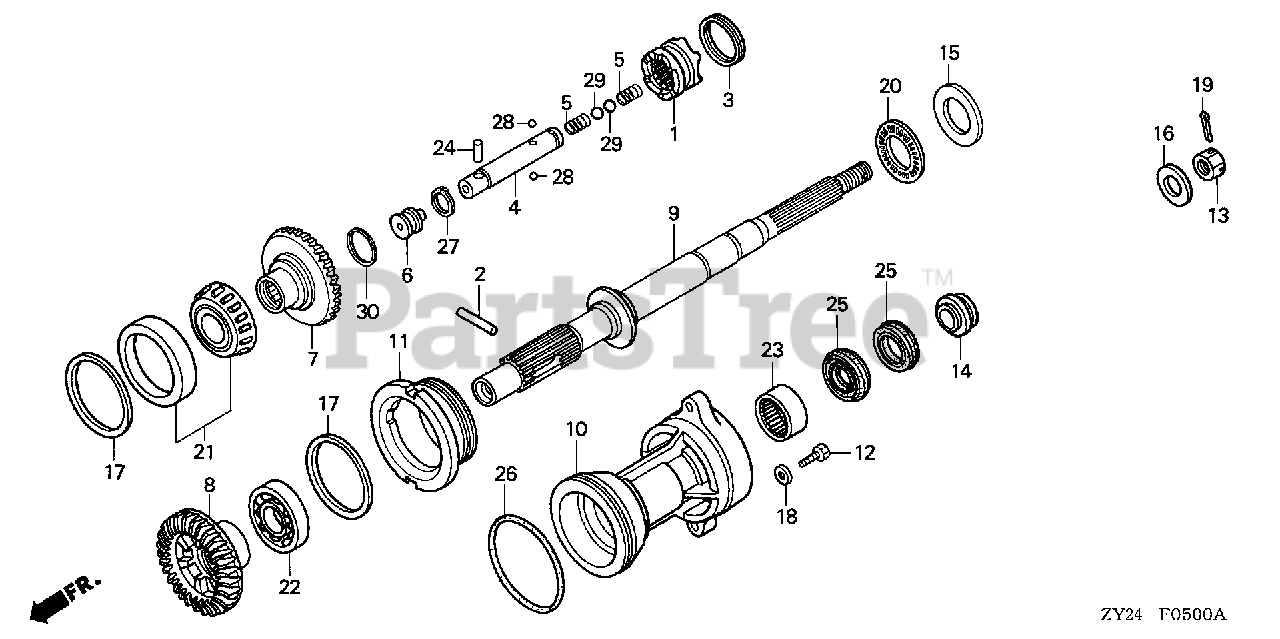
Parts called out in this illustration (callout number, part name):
1	SHIFTER, CLUTCH
2	PIN, SHIFTER (8X50)
3	RING, CROSS PIN
4	SLIDER, SHIFT
5	SPRING, SHIFT
6	PLATE, SHIFT
7	GEAR, FR. BEVEL (28T)
8	GEAR, BEVEL (RVS. 28T)
9	SHAFT, PROPELLER
10	HOLDER, PROPELLER SHAFT *NH282MU* (OYSTER SILVER METALLIC-U)
11	HOLDER, BEARING
12	BOLT, HEX. (12X45)
13	NUT, CASTLE (18MM)
14	WASHER, PROPELLER THRUST
15	WASHER, THRUST BEARING
16	WASHER, PROPELLER
17	SHIM A, BEVEL (0.10)
17	SHIM B, BEVEL (0.15)
17	SHIM C, BEVEL (0.30)
17	SHIM D, BEVEL (0.50)
18	WASHER, PLAIN (12MM)
19	PIN, SPLIT (4.0)
20	BEARING, THRUST (F)
21	BEARING, TAPER (50X90X21.5)
22	BEARING, ANGULAR (50X90X30.2)
23	BEARING, NEEDLE (32X42X30)
24	ROLLER (4X13.8)
25	SEAL, WATER (30X45X7)
26	O-RING (105X3.1)
27	CIRCLIP (OUTER) (15MM)
28	BALL, STEEL (#7) (7/32)
29	BALL, STEEL (#12) (3/8)
30	SHIM A, THRUST (2.75)
30	SHIM B, THRUST (2.80)
30	SHIM C, THRUST (2.85)
30	SHIM D, THRUST (2.90)
30	SHIM E, THRUST (2.95)
30	SHIM F, THRUST (3.00)
